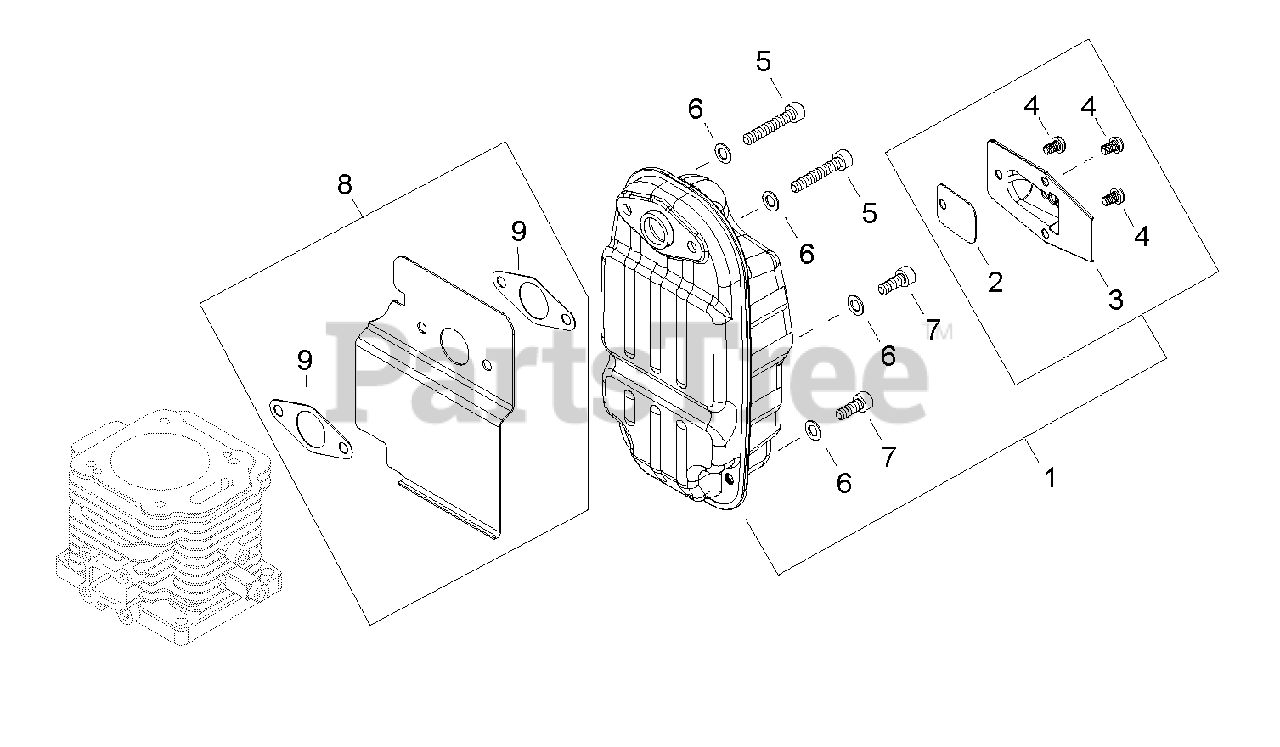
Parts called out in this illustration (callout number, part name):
1	MUFFLER ASSY
2	SCREEN, SPARK ARRESTER
3	GUIDE, EXHAUST
4	SCREW M5×8
5	BOLT SS M6×35
6	WASHER 6.5×11.5×0.8
8	DEFLECTOR ASSY, EXHAUST HEAT
9	GASKET, EXHAUST
